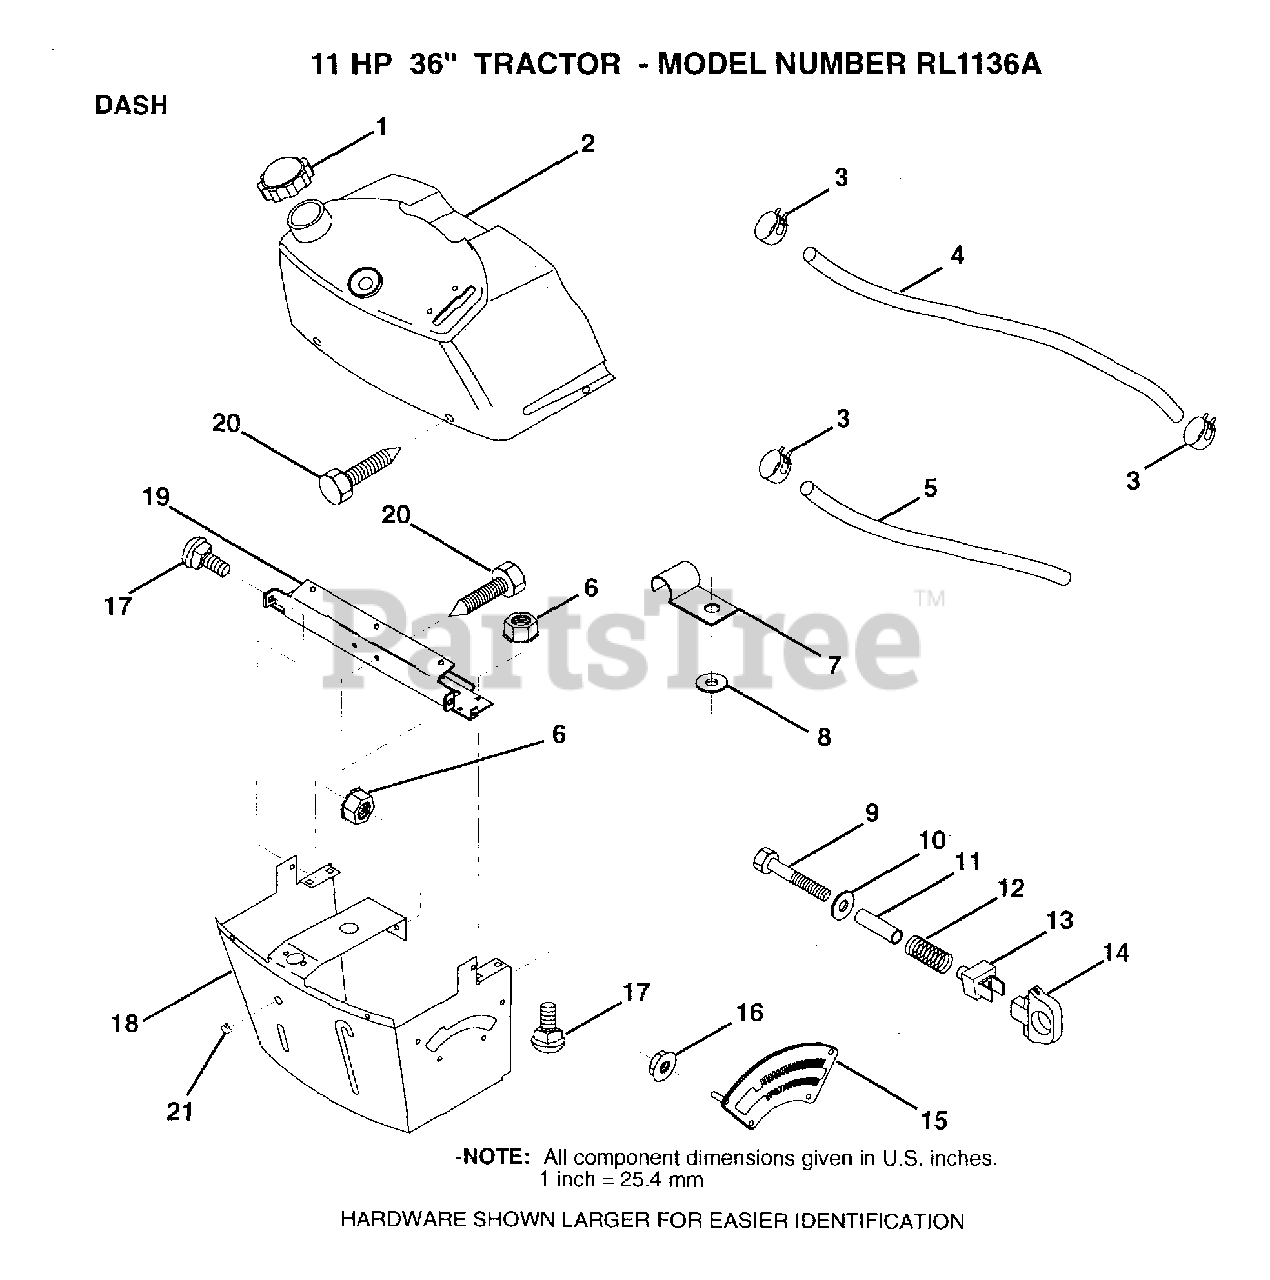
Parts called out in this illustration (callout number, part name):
1	CAP.FUEL.N/VENT
2	TANK.ASM.DASH.LR
3	HOSE CLAMP
5	FUEL LINE T
6	NUT
7	CLIP T
8	WASHER PM
9	BOLT
11	SPACER SPLIT
12	SPRING M
13	"KNOB,HGT RETAINER"
14	KNOB
15	ADJUSTER QUAD
16	NUT
17	BOLT
18	SUPT ASSY DASH
19	CROSS BRACE
20	SCREW.1/4-20X1/2
21	PLUG DOME
